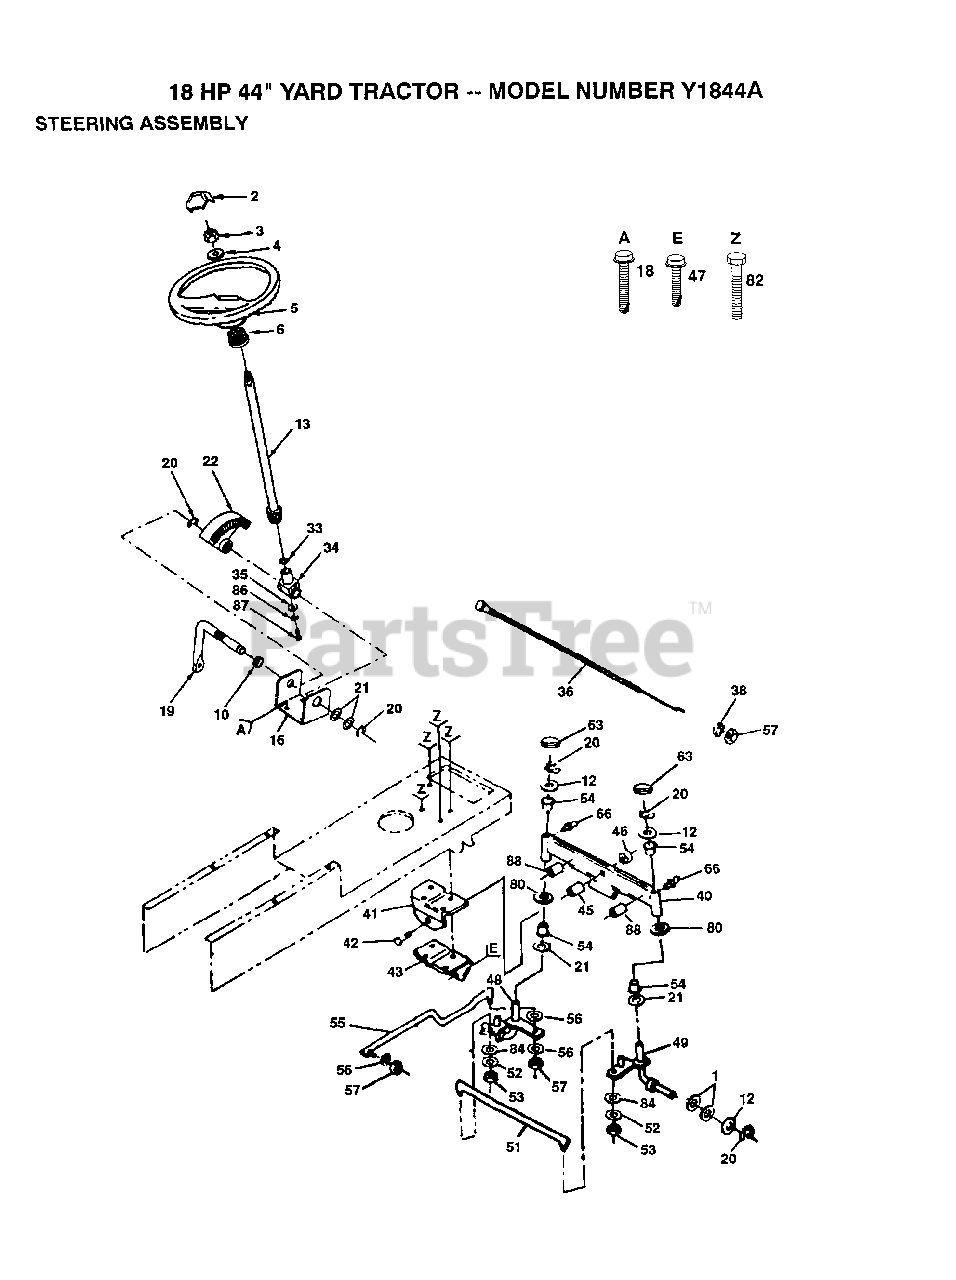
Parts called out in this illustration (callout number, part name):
1	WASHER
2	INSERT STEERING
4	WASHER
6	ADAPTER LT
10	NYLINER T
12	WASHER
16	"BRKT,STEERING"
18	SCREW
20	RING
21	WASHER .T
33	THRUST WASHER
34	SUPPORT.SHAFT
36	CHOKE CONTROL
38	LOCKWASHER
40	FRONT AXLE
41	SUPPORT-SADDL T
42	BOLT LT
43	SUPPORT.SADDLE.FT
45	BEARING
47	SCREW LT
49	SPINDLE ASM RH
51	TIE ROD
52	LOCKWASHER
53	NUT.LOCK.5/16-24
54	COL. SRTG. BEAR.
56	LOCKWASHER
63	CAP
66	ZERK M
80	WASHER
82	SCREW SPECIAL
84	WASHER M
86	LOCKWASHER
87	"SCREW,SPECIAL"
88	AXLE PIN
